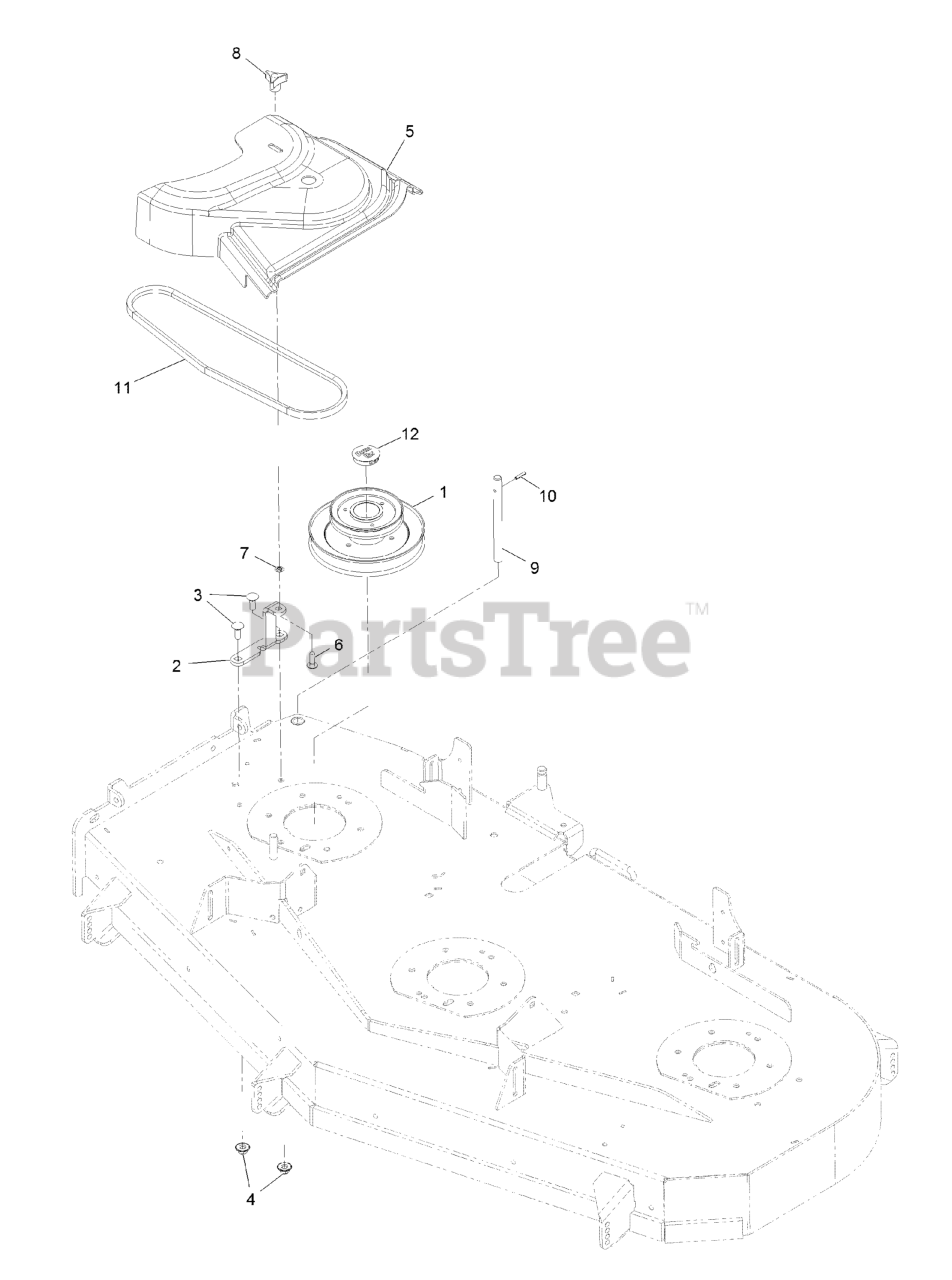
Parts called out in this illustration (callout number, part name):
1	JACKSHFT- UV DRIVE 603
2	BRACKET-BELT COVER
3	BOLT-CARR
4	Nut-Nyloc 3/8-16 Flg
5	COVER-BELT, UV 60 ENTRY
6	BOLT-CARR
7	RING-RETAINING, BOLT
8	KNOB-3 PRONG
9	SHAFT-CATCHER, GRASS
10	PIN-ROLL
11	V-BELT (17569)
12	PLUG, BLACK NYLON 1.75
